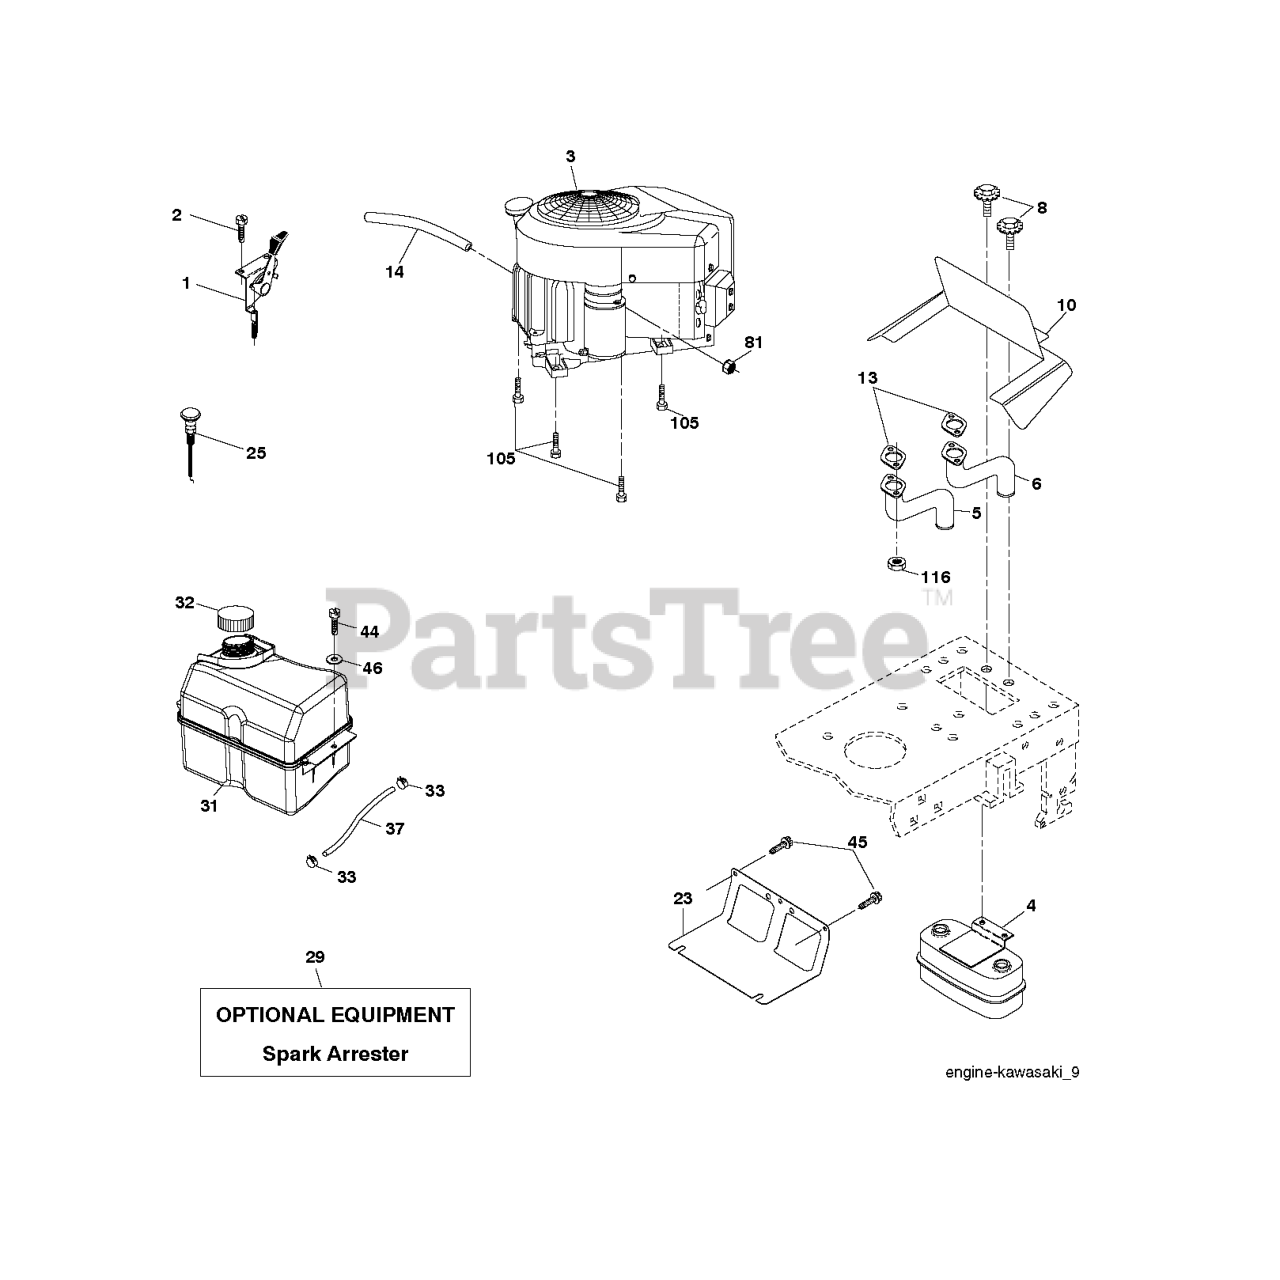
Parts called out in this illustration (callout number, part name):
1	THROTTLE CABLE
2	SCREW
4	MUFFLER.TWIN.CYL.LOW.TONE
5	EXHAUST TUBE LH KAWI
6	EXHAUST TUBE RH KAWI
8	BOLT.5/16-18UNCX3/4 W/SEMS.BLK
10	RP SHIELD HEAT MUFFLER
14	TUBE, DRAIN OIL ASM.
23	SHIELD.BROWNING.DBR.GUARD
25	CONTROL, CHOKE
29	KIT.SPARK ARRESTOR 794945 B&S
31	TANK FUEL
32	FUEL CAP
33	HOSE CLAMP
37	LINE.FUEL.20
44	SCREW HEXWSHR 1/4-20X3/4
45	SCREW, 3/8-16X3/4
81	NUT
105	SCREW 3/8-16X1
116	NUT.HEX.FLANGE.TOPLOCK
